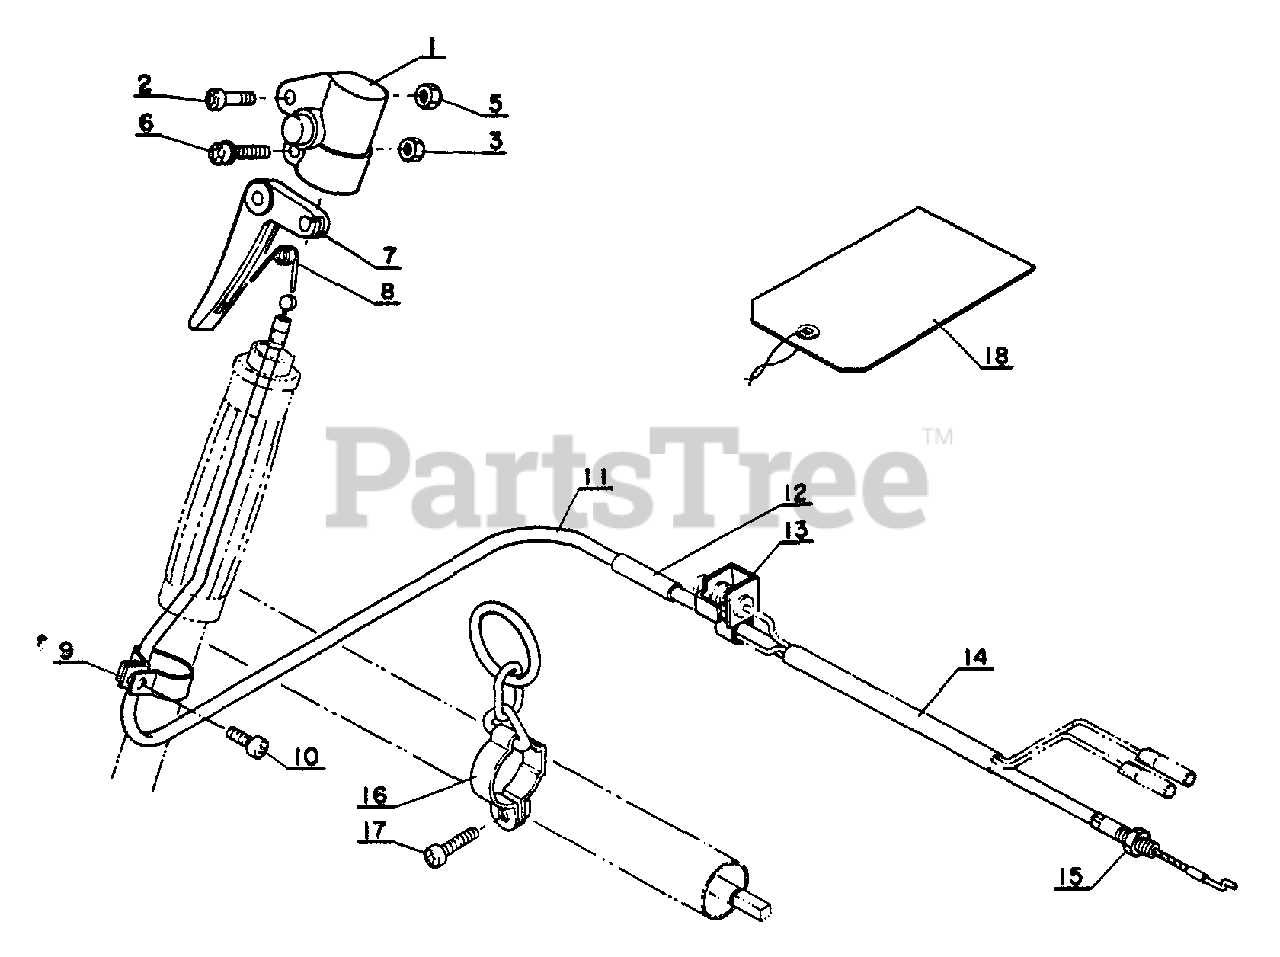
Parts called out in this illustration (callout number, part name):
1	CLAMP, THROTTLE CONTROL
2	SCREW - 5X30
5	LOCKNUT - 5
6	SCREW - 5X28
7	TRIGGER, THROTTLE
8	SPRING, TRIGGER
10	SCREW - 5X10
11	CABLE, THROTTLE
12	TUBE
14	TUBE
16	HANGER KIT
17	SCREW - 5X12
